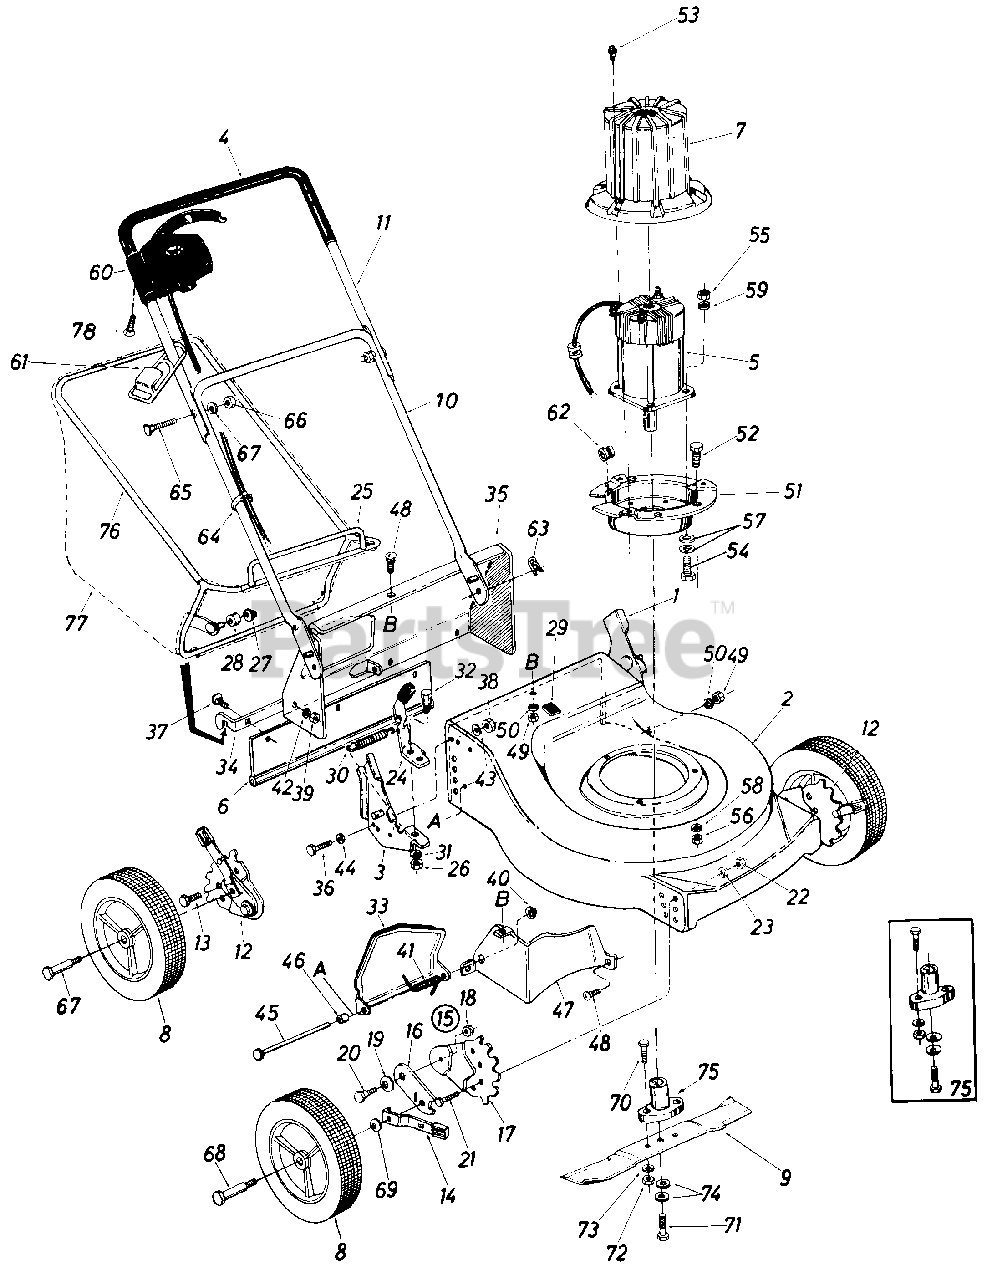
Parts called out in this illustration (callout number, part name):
1	Handle Brk't. Ass'y. L.H.
2	20" Deck Ass'y.
3	Handle Brk't. Ass'y. R.H.
6	Rear Flap Ass'y.
7	Shroud
8	Plastic Wheel 8 x 1.75
9	20" Blade
10	Lower Handle (Chrome)
11	Upper Handle (Chrome)
12	Height Adjust. Ass'y. L.H.
13	Hex Bolt 3/8-16 x .75" Lg.
14	Spring Lever Ass'y. w/Knob
15	Height Adjust. Ass'y. R.H.
16	Pivot Bar
17	Index Plate
18	Hex Cent. L-Nut 3/8-16 Thd.
19	Bell-Wash. .515" I.D. x 1.14" O.D.
20	Shld. Bolt .500" Dia. x .295"
21	Hex Bolt 3/8-16 x .75" Lg.
22	Hex Nut 3/8-16 Thd.
23	L-Wash. 3/8 I.D.
24	Grass Catcher Lock Lever w/Knob
27	Push Nut 3/8" Rod
28	Plastic Roller
30	Extension Spring
31	L-Wash. 5/16" I.D.
32	Shld. Bolt .437" Dia. x .162"
33	Chute Door
34	Grass Catcher Hitch Brk't.
35	Rear Deck Secti on
36	Hex Bolt 1/4-28 x .75" Lg.
37	Carr. Bolt 1/4-20 x .75" Lg.
38	Hex Nut 1/4-28 Thd.
39	Sems Nuts 1/4-20 Thd.
40	Push Nut 1/4" Rod
41	Torsion Spring
42	Fl-Wash. .285" I.D. x 1.25" O.D.
43	Bell-Wash. 1/4" I.D. x .88" O.D.
44	L-Wash. 1/4" I.D.
45	Hinge Pin
46	Spacer
47	Rear Baffle
48	Carr. Bolt 1/4-20 x .50" Lg.
49	Hex Nut 1/4-20 Thd.
50	L-Wash. 1/4" I.D.
51	Adapter Plate
52	Hex Bolt 3/8-16 x 1.00" Lg.
53	Hex Wash. Hd. F-Tap Scr. #10-32 x .314" Lg.
54	Hex Bolt 1/4-20 x 1.00" Lg.
55	Hex Nut 1/4-20 Thd.
56	Hex Nut 3/8-16 Thd.
57	Fl-Wash. 3/8 I.D. x 1.0" O.D.
58	L-Wash. 3/8" I.D.
59	L-Wash. 1/4" I.D.
60	Control w/Cord
61	Restraint
62	Cord Restraint
63	Inter. Cot-Pin 5/16" Dia.
64	Cable Tie
65	Curve Carr. Bolt 5/16-18 x 1.38" Lg.
66	Hex Nut 5/16-18 Thd.
67	L-Wash. 5/16" I.D.
68	Bell-Wash. .400" I.D. x .88" O.D.
69	Shld. Bolt .498" Dia. x 1.450"
70	Hex Bolt 5/16-24 x 1.00" Lg.
71	Hex Bolt 5/16-24 x .75" Lg.
72	Hex Nut 5/16-24 Thd.
73	L-Wash. 5/16" I.D.
74	Bell-Wash. .345" I.D. x .88 O.D.
75	Blade Adapter Kit
76	Grass Catcher Upper Frame
77	Grass Bag
78	Truss Mach. AB-Tap Scr.
